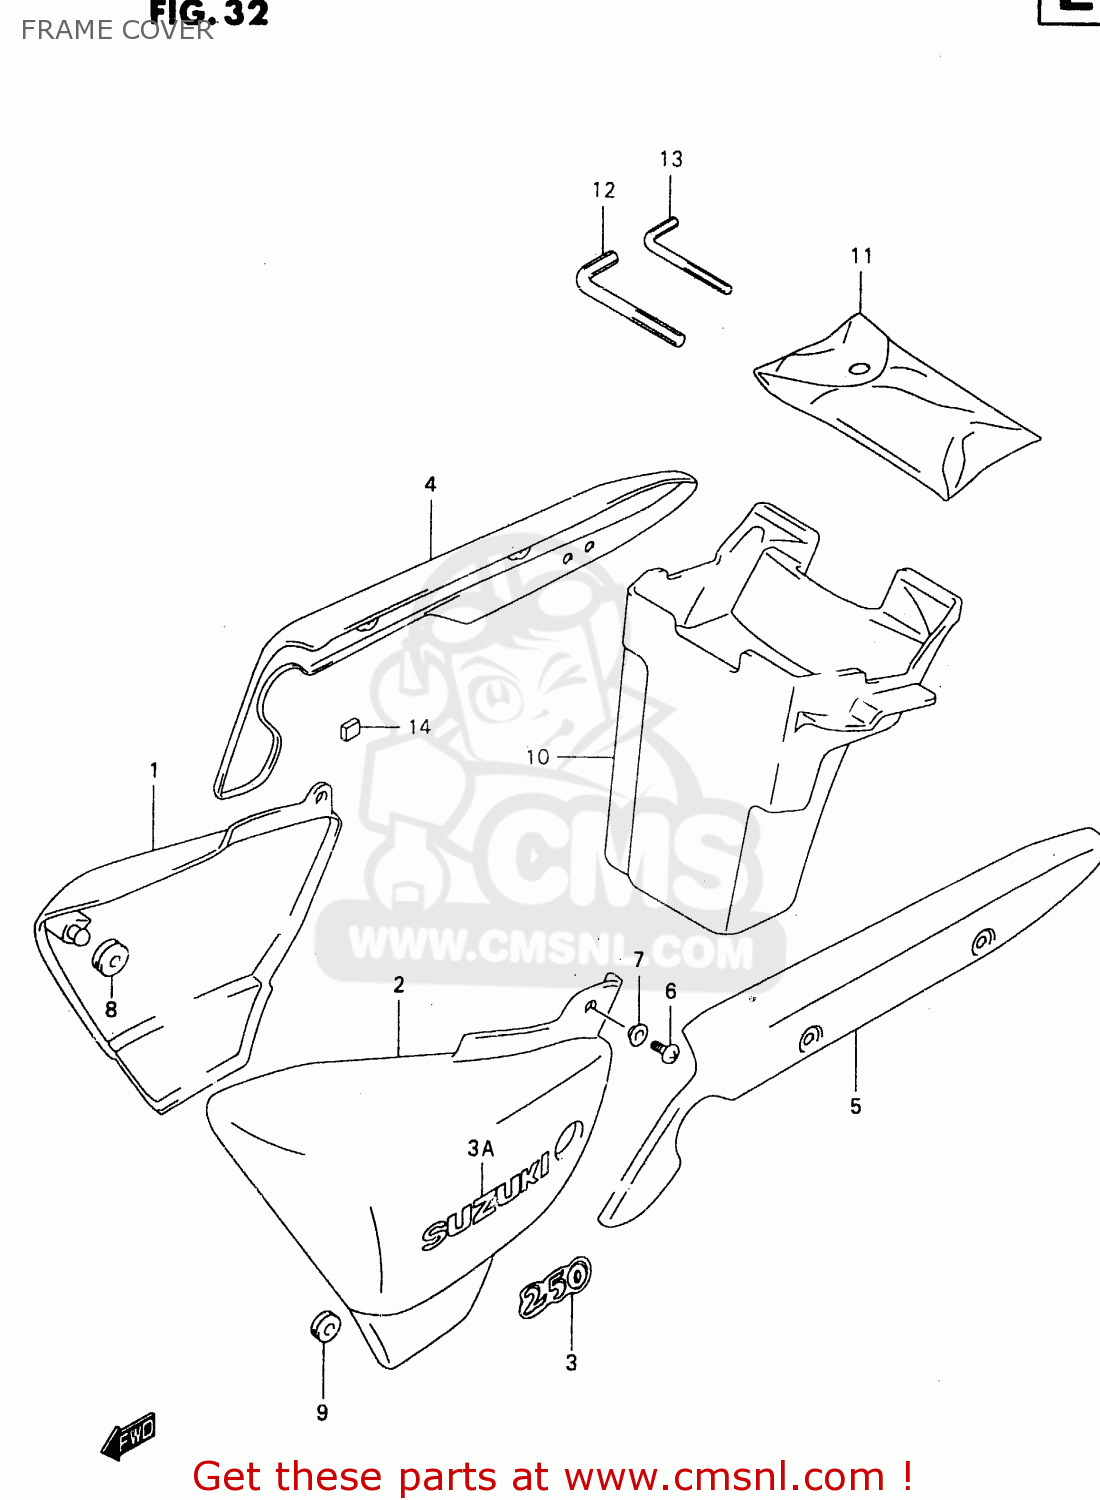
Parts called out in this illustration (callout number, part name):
1	COVER,FRAME,RIGHT
2	COVER,FRAME,LEFT
3	EMBLEM,250
3A	EMBLEM,FRAME COVER
4	COVER,FRAME RR,R
5	COVER,FRAME RR,L
6	SCREW 6X12
7	WASHER
8	CUSHION
9	CUSHION
10	BODY,LUGGAGE BOX
11	TOOL ASSY
12	SPANNER,HEXAGON(6)
13	SPANNER,HEXAGON(4)
14	CUSHION
